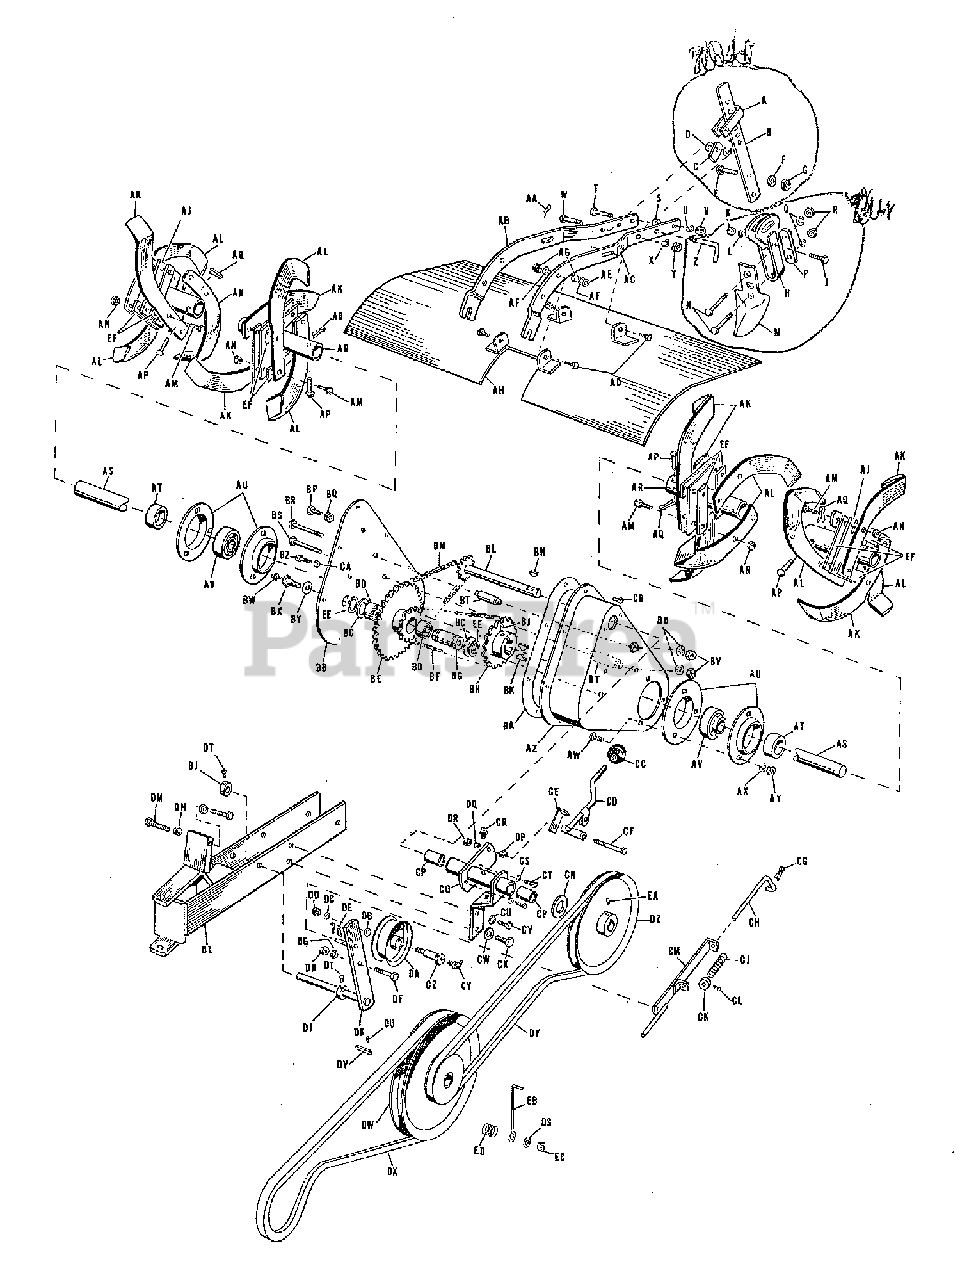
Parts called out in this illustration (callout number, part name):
B	BAR, Depth
C	LUG, Stop
D	WASHER, Plain, 7/16"
E	BOLT, Carriage, 3/8"-16 x 1-1/4" Lg w/Short Square Neck
F	WASHER, Plain, 3/8"
G	NUT, Hex, Full, 3/8"-16
H	HOLDER ASSEMBLY, Tool
J	CAPSCREW, Hex, 3/8"-16 x 1-1/2" Lg.
K	NUT, Hex, Full, 3/8"-16
L	WASHER, Lock, 3/8"
M	SHOE, Depth
N	BOLT, Plow, 3/8"-16 x 2-1/4" Lg.
P	STRAP, Shoe
Q	WASHER, Lock, 7/16"
R	NUT, Hex, Full, 7/16"
T	CAPSCREW, Hex, 1/2"-13 x 2" Lg.
U	WASHER, Lock, 1/2"
V	NUT, Hex, Full, 1/2"-13
W	CAPSCREW, Hex, 1/2"-13 x 2 1/4" Lg.
X	WASHER, Lock, 1/2"
Y	NUT, Hex, Full, 1/2"-13
AA	CLIP, Spring
AB	BEAM, Depth Gage, R.H.
AC	BEAM, Depth Gage, L.H.
AD	CAPSCREW, Hex, 3/8"-16 x 1" Lg.
AE	WASHER, Plain, 3/8"
AF	WASHER, Lock, 3/8"
AG	NUT, Hex, Full, 3/8"-16
AH	DEFLECTOR ASSEMBLY
AJ	PLATE ASSEMBLY, Tine, Outer
AK	BLADE, R.H. Tine
AL	BLADE, L.H. Tine
AM	CAPSCREW, Hex, 7/16"-20 x 1-3/4" Lg.
AN	NUT, Hex, Full Lock, 7/16"-20 Gripco
AP	PIN, Tine, Shaft
AQ	PIN, Cotter, 1/8" x 3/4" Lg.
AR	PLATE ASSEMBLY, Tine, Inner
AS	SHAFT, Tine
AT	COLLAR, Bearing
AU	FLANGE, Bearing
AW	BOLT, Carriage, 3/8"-16 x 3/4" Lg.
AX	WASHER, Lock, 3/8"
AY	NUT, Hex, Full, 3/8"-16
AZ	GUARD ASSEMBLY, Chain
BB	PLATE ASSEMBLY, Side
BD	BEARING, Roller
BE	SPROCKET ASSEMBLY
BF	CHAIN, Rotor
BG	SPACER, Intermediate
BH	SPROCKET, Driven
BJ	SETSCREW, Socket Head, 5/16"-18 x 5/16"
BK	KEY, Hi-Pro
BL	SHAFT ASSEMBLY, Drive
BM	CHAIN, Drive
BN	KEY, Woodruff, #9, 3/16 x 3/4"
BP	SETSCREW, Square Head, 3/8"-24 x 3/4" Lg.
BQ	NUT, Hex Jam, 3/8"-24
BR	CAPSCREW, Hex, 7/16"-14 x 4-1/2" Lg.
BS	CAPSCREW, Hex, 7/16"-14 x 3-3/4" Lg.
BT	SPACER, Guard
BU	WASHER, Lock, 7/16" Intermediate Shakeproof
BV	NUT, Hex, Full, 7/16"-14
BW	FITTING, Grease, Alemite #1641
BY	WASHER, Plain, 7/16"
BZ	CAPSCREW, Hex, 3/8"-16 x 3/4" Lg
CA	WASHER, Lock, 3/8"
CB	SCREW, 1/4"-20 x 3/8" Hex Head, Sems w/External Lockwasher
CC	BALL, Clutch Lever
CD	CLUTCH LEVER ASSEMBLY, R.H.
CE	STOP, Lever
CF	CAPSCREW, Hex, 5/16"-18 x 2-1/2"
CG	PIN, Cotter, 3/32" x 3/4" Lg.
CH	ROD, Idler Clutch
CK	COLLAR, Set
CL	SETSCREW, Square Head, 1/4"-20 x 3/8"
CM	GUIDE ASSEMBLY, Rod
CQ	SUPPORT ASSEMBLY, Housing
CR	FITTING, Grease, Alemite #1792
CS	WASHER, Lock, 5/16"
CT	CAPSCREW, Hex, 5/16"-18 x 3/4"
CU	WASHER, Lock, 3/8" Intermediate Shakeproof
CV	CAPSCREW, Hex, 3/8"-16 x 7/8" Lg.
CW	WASHER, Plain, 7/16"
CX	CAPSCREW, Hex, 1/2"-20 x 1-3/4"
CY	FITTING, Grease, Alemite, #1911-90 Degrees
CZ	PIN, Idler Pulley
DA	PULLEY ASSEMBLY, Idler
DC	WASHER, Lock, 1/2" Intermediate Shakeproof
DD	NUT, Hex Jam, 1/2"-20
DE	PIN, Cotter, 1/8" x 1" Lg.
DF	CAPSCREW, Hex, 3/8"-16 x 1-1/2"
DG	WASHER, Lock, 3/8"
DH	NUT, Hex, Full, 3/8"-16
DJ	SET COLLAR
DK	LEVER ASSEMBLY, Idler
DL	FRAME ASSEMBLY
DM	CAPSCREW, Hex, 7/16"-20 x 1-1/2"
DN	NUT, Hex, Full, 7/16"-20
DP	NUT, Hex, Jam, 5/16"-18
DQ	WASHER, Lock, 5/16"
DR	NUT, Hex, Full, 5/16"-18
DS	WASHER, Plain, 3/8"
DT	SETSCREW, Square Head, 5/16"-18 x 3/8"
DU	SETSCREW, Socket Head, 5/16"-18 x 5/16" Lg.
DW	SHEAVE ASSEMBLY, Transmission
DX	BELT, "V", (Engine)
DY	BELT, "V", (Tiller)
EA	SETSCREW, Socket Head, 5/16-18 x 5/16" Lg.
EB	STOP, Belt
EC	NUT, Lock, Full Hex, 3/8"-16
EE	RING, Retaining
